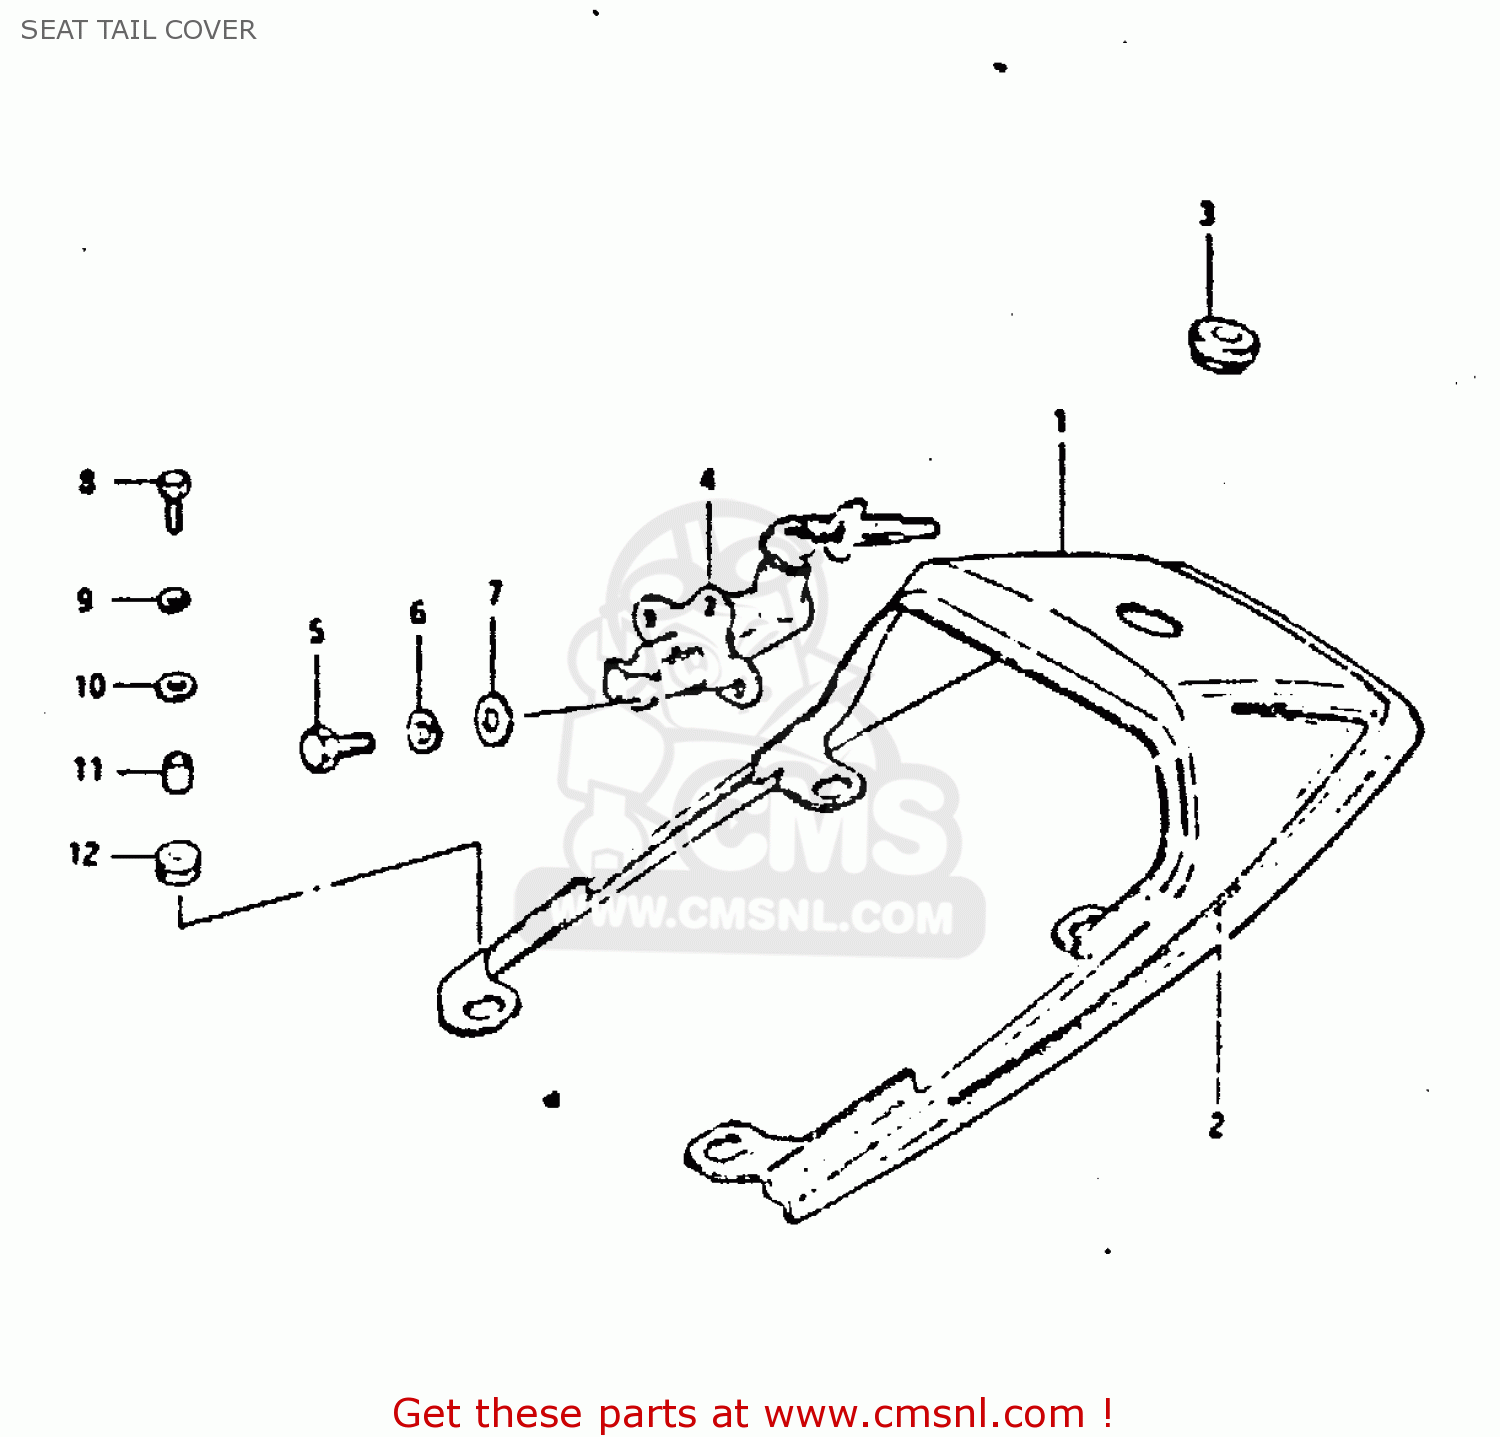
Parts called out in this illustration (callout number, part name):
1	BOX ASSEMBLY,SEAT TAIL
2	TAPE SET,BOX SEAT TAIL
3	GROMMET,SEAT LOCK HOLE
4	LOCK SET,SEAT
5	BOLT
6	LOCK WASHER
7	WASHER
8	BOLT
9	LOCK WASHER
10	WASHER(6,5X22X1.6)
11	CUSHION
12	SPACER(6.5X10.5X12)
